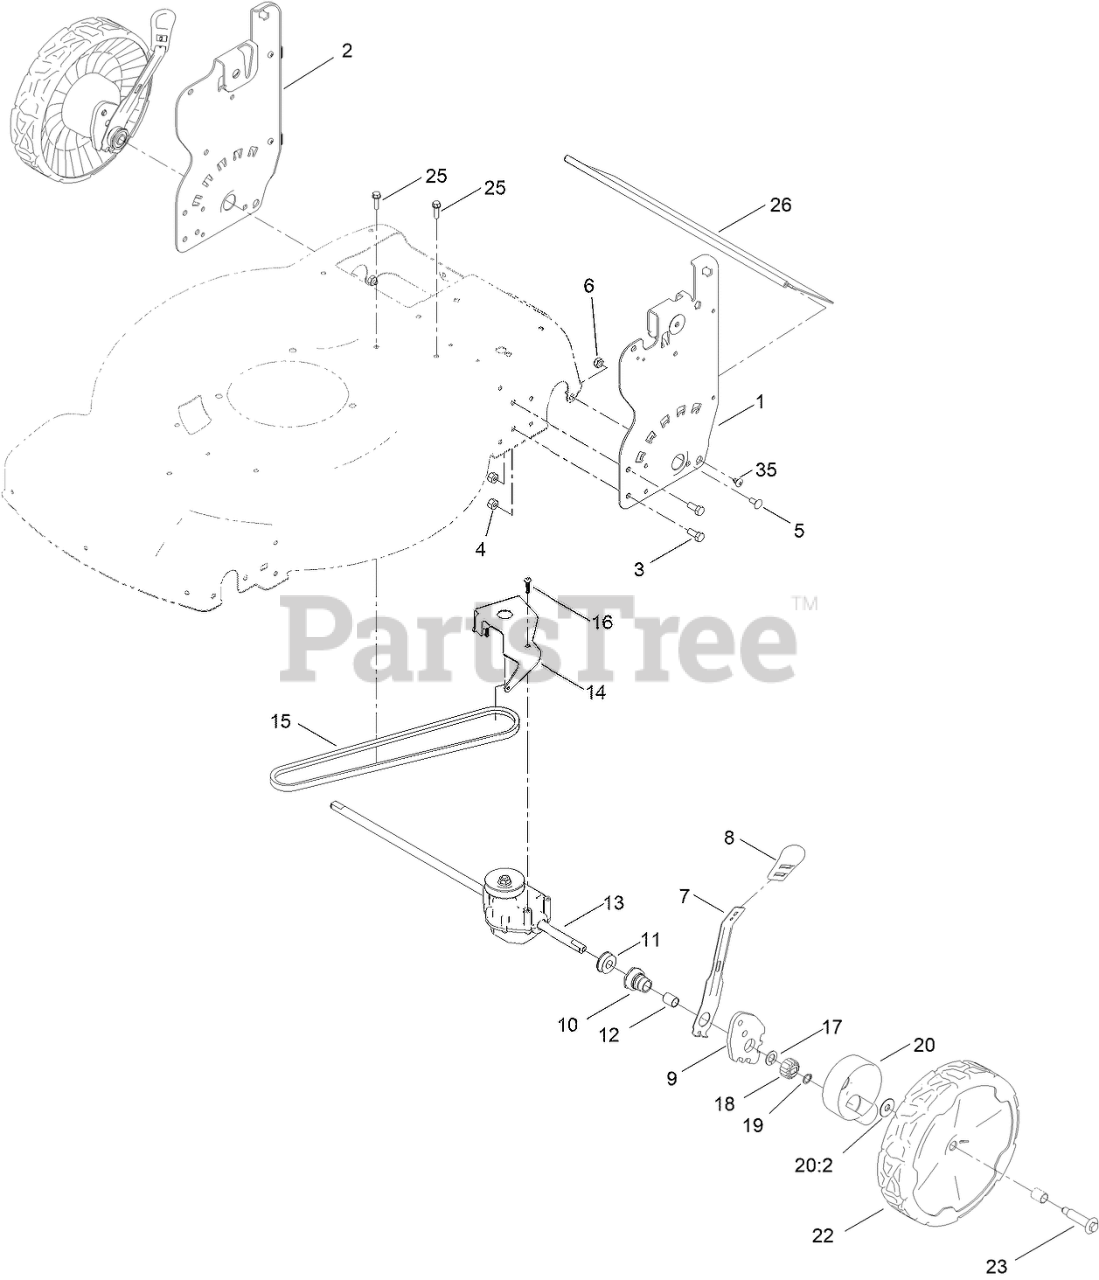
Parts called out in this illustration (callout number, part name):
1	PLATE-HOC, LH (ISO)
2	PLATE-HOC, RH (ISO)
3	SCREW-HH
4	NUT-HEX
5	BOLT-CARR
6	NUT-LOCK
7	ARM-SPRING
8	KNOB-HOC
9	ARM-PIVOT, REAR
10	RETAINER-BUSHING, HOC
11	BEARING-BALL
12	BUSHING-SLEEVE
13	TRANSMISSION-RWD
14	BRACKET-TRANSMISSION
15	V-BELT
16	SCREW-PLASTITE
17	WASHER-THRUST
18	GEAR-PINION, 15T
19	RING-RETAINING
20	ASM-COVER, GEAR (DK GRAY)
20:2	WASHER-STEPPED
22	ASM-9.65" WHEEL, GEARED
23	WHEEL BOLT
25	SCREW-PLASTITE, HWH
26	SHIELD-TRAILING
35	SCREW-THD
